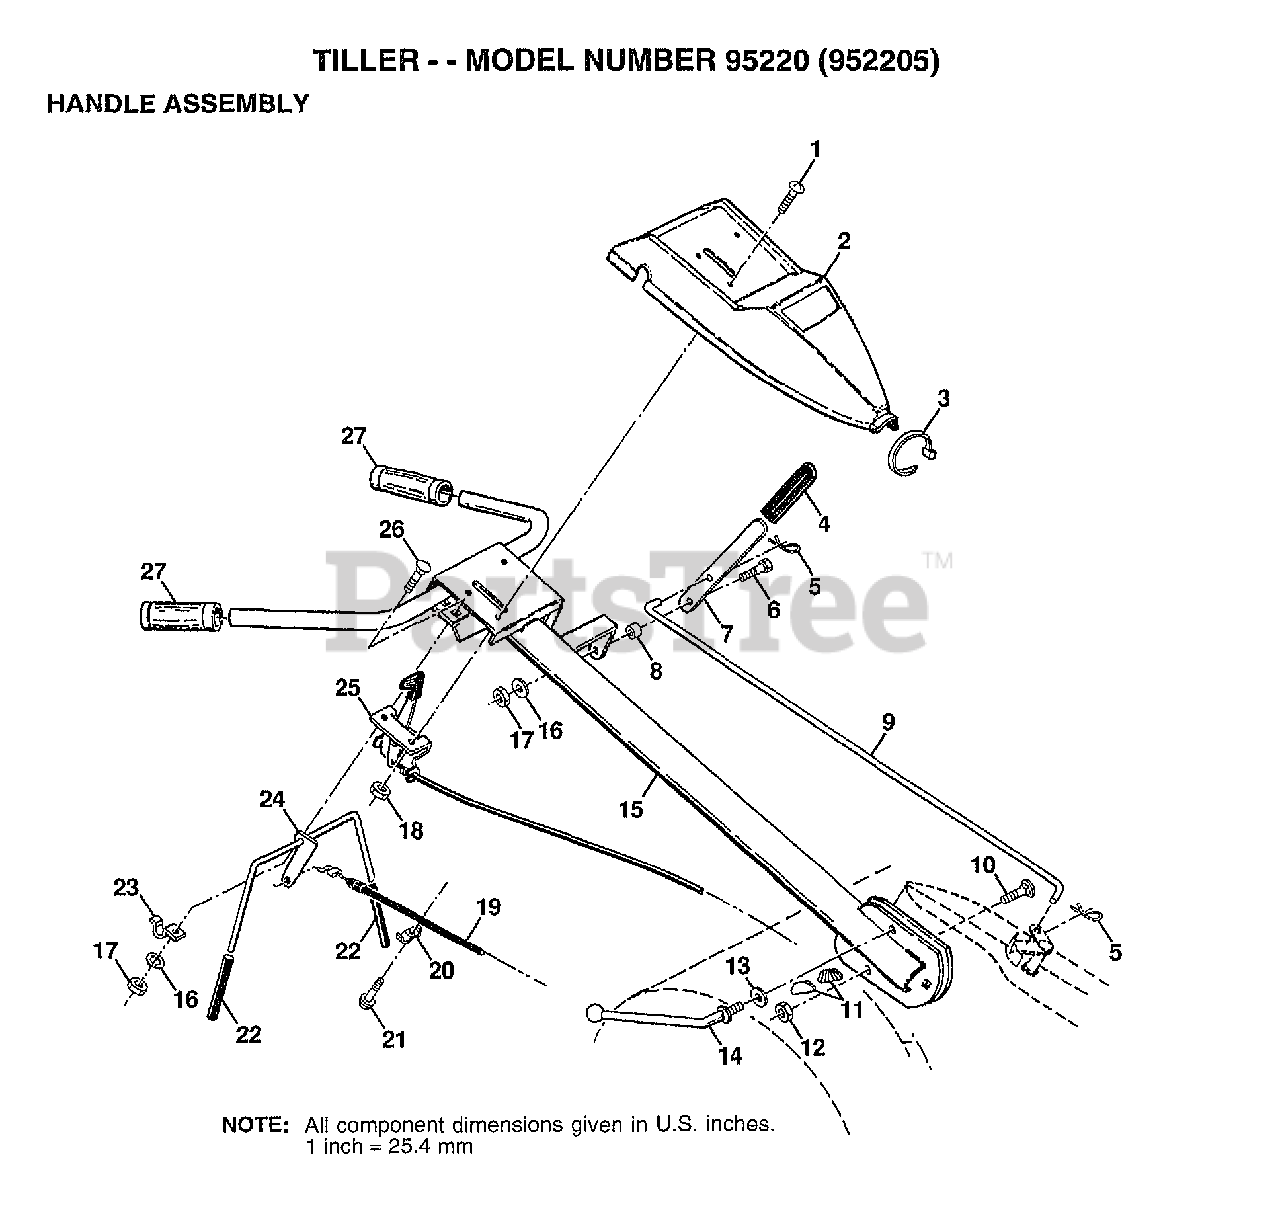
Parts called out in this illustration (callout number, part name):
1	SCREW.PNHD.10-24
2	"PANEL,CONT TI"
3	TIE CABLE CRT
4	GRIP T
5	RETAINER M
6	SHOULDER BOLT ST
7	SHIFT HANDLE CRT
8	GROMMET CRT
9	SHIFT ROD CRT
10	BOLT D
11	LOCK CRT
12	LOCKNUT
13	WASHER CRT
14	LEVER LOCK CRT
16	LOCKWASHER
19	CABLE.CLUTCH.48.Z
20	CONDIUT CLIP T
22	GRIP BAR CRT
24	"ASSY CONTROL, BAR"
25	"CONT,THROTTLE"
26	BOLT
27	GRIP NUB SNGL HDL
